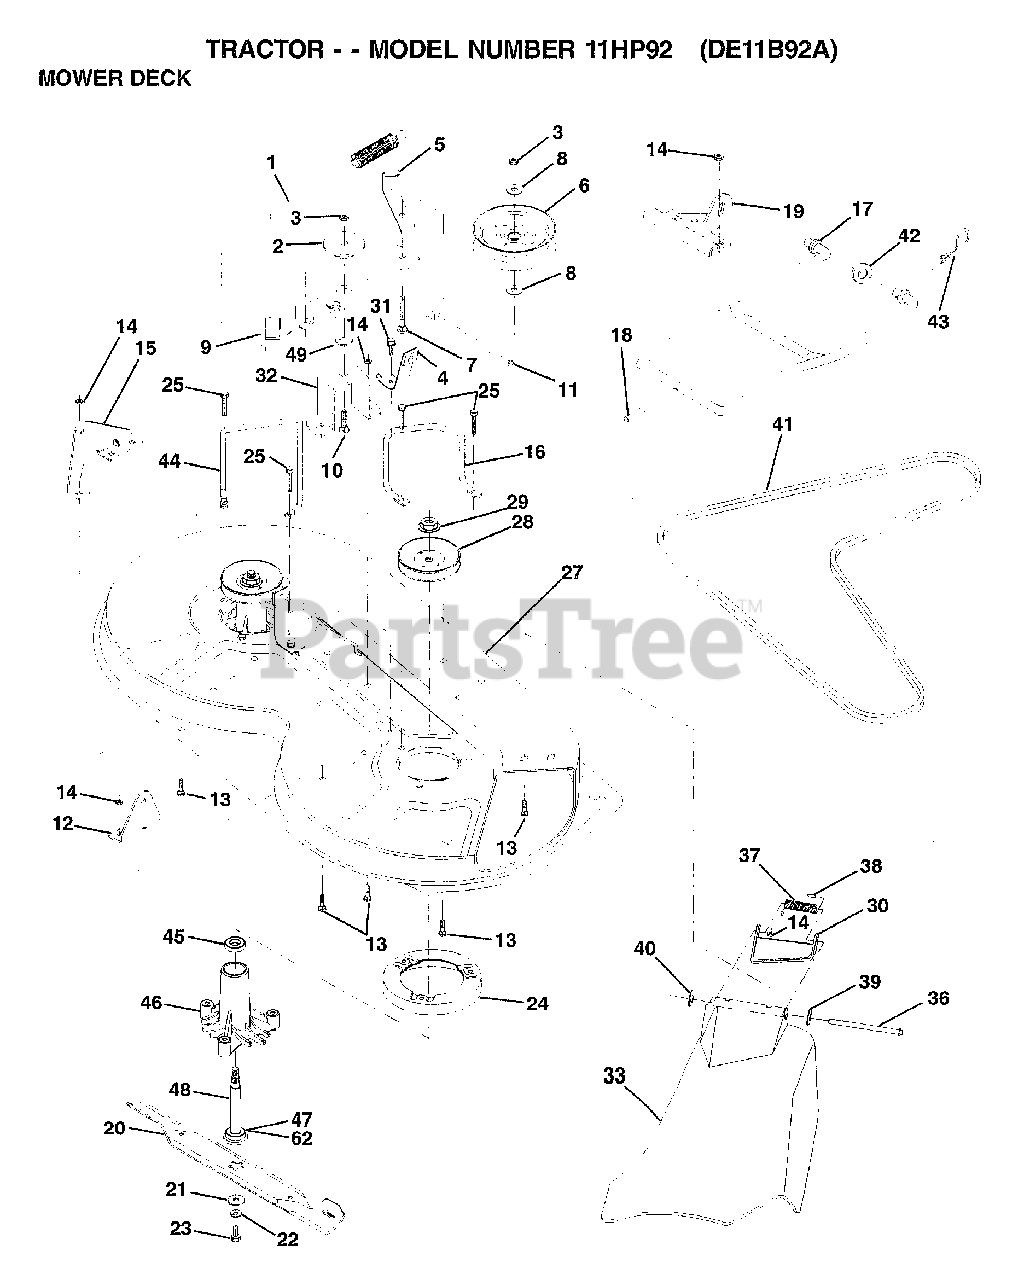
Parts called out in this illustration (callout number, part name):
1	SPRING CLUTCH MWR
2	SPACER.RETAINER.MOWER
4	BRAKE ASM
5	IDLER BELT GUIDE
6	PULLEY IDLER
7	BOLT
8	WASHER
10	BOLT.3/8-14X1.25
11	BRAKE ROD
12	"BRKT,LIFT REAR"
13	BOLT
15	"BRKT,LIFT REAR LH"
16	"KEEPER-BELT,RH"
17	MOWER LINK STAB
18	"PIN,GROOVE"
19	"BRKT,LINK STABILI"
20	"BLADE.36"" HIPERF"
21	WASHER.HARD.BLADE
23	BLADE BOLT
24	STRIPPER RND MWR
25	"SCREW-THD ROLL,WA"
27	"HOUSING-MOWER,36"""
28	PULLEY.MAND.36/46
31	SCREW LT
32	"SUPT,IDLER ARM"
33	SHIELD, DEFLECTOR
36	HINGE ROD
37	SPRING TORSION
38	CAP-SLEEVE LT
39	WASHER
40	NUT PUSH M
41	V-BELT.PRIM.78.5.
43	RETAINER.SPRING
44	KEEPER BELT LH
45	BEARING
46	HSG ASM MANDREL
47	BEARING.BALL
49	HARDENED WASHER
62	WASHER.FELT.
